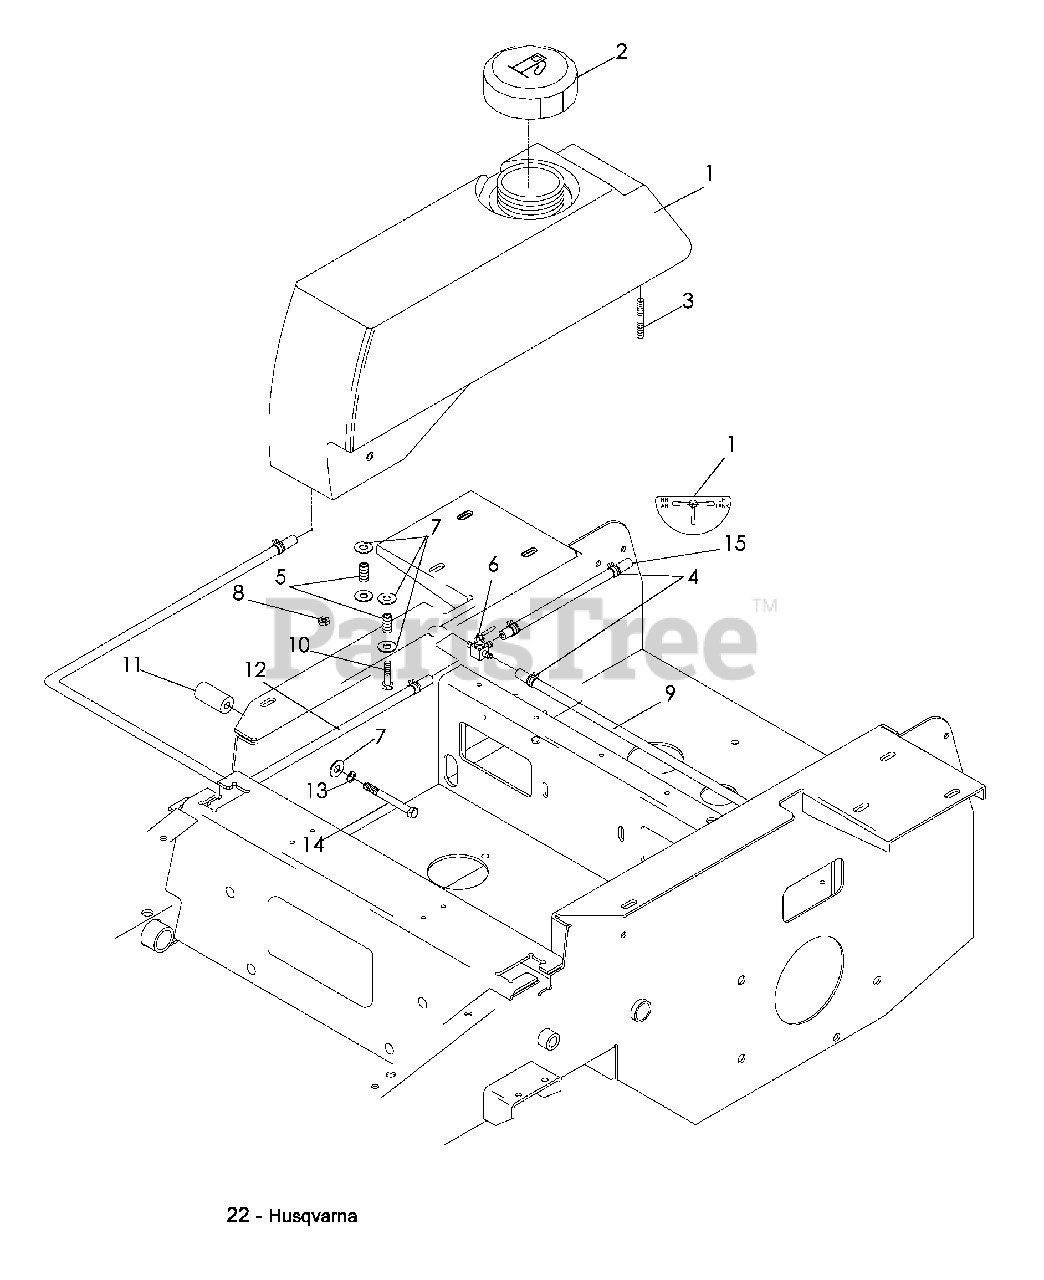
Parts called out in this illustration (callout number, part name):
1	FUEL TANK RT
2	FUEL CAP
4	HOSE CLAMP
6	FUEL VALVE
7	WASHER 5/16 STD FLT
8	NUT 5/16-18 CENTERLOCK
10	HCS 5/16-18 x 1
11	TANK SP ACER
13	WASHER 5/16 LOCK
14	HCS 5/16-18 x 4
16	DECAL, FUEL LINE
